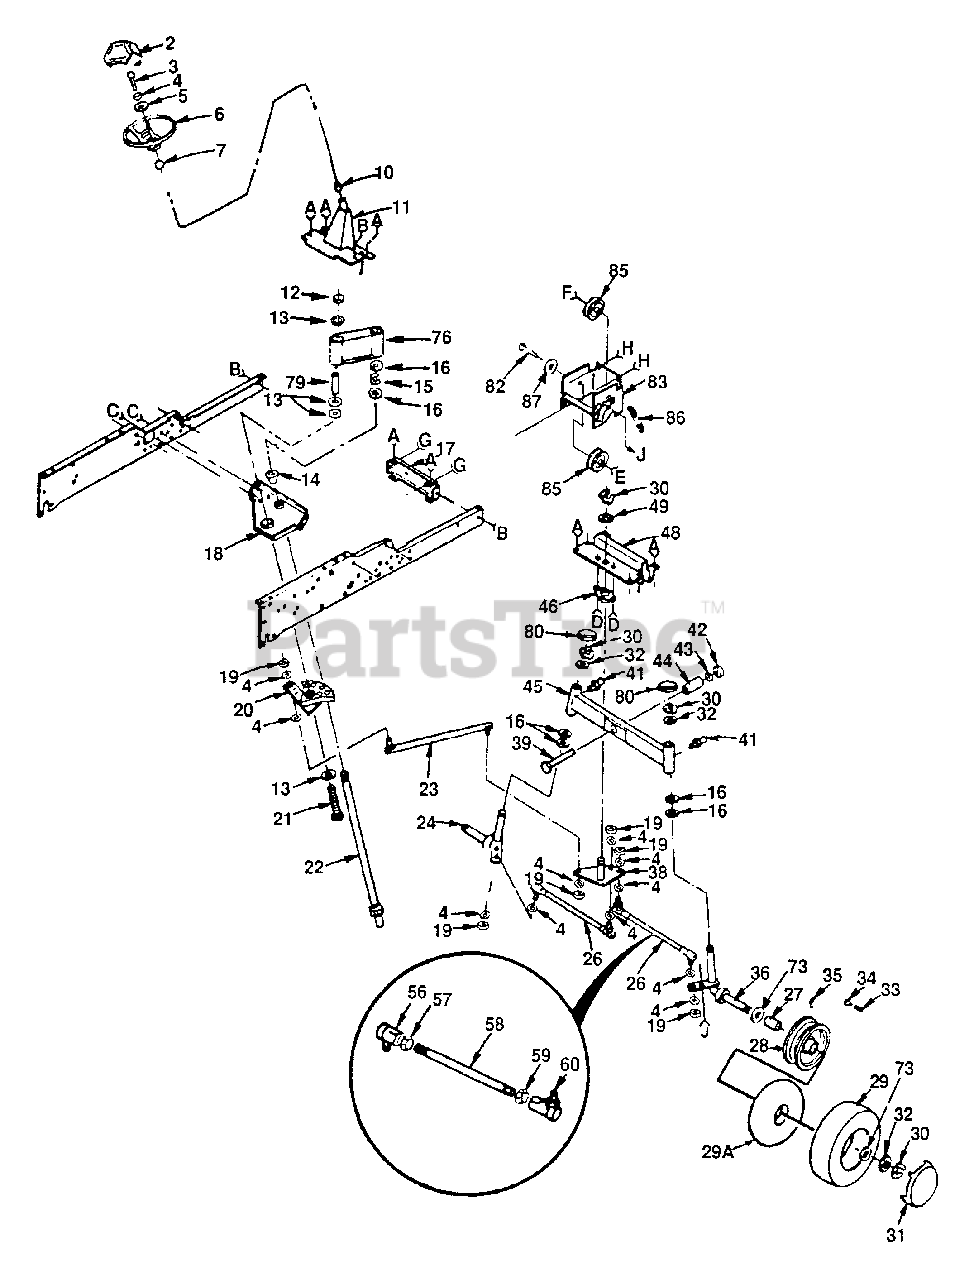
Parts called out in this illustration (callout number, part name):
2	Insert, Steering Wheel
3	Bolt, Hex 3/8-16 x 1 Grade 5
4	Washer, Lock 3/8
5	Washer 13/32 x 2-3/8 x 8 Gauge
6	Wheel, Steering
7	Adapter, Steering
11	Support Assembly, Steering
12	Locknut 1/2-13
13	Washer 17/32 x 1-5/8 x 10 Gauge
14	Bearing, Flanged
16	Bearing, Thrust
17	Bracket, Frame, Front
18	Bracket, Support, Steering
19	Nut, Hex 3/8-24
20	Sector Assembly
21	Bolt, Hex 1/2-13 x 5 Grade 5
22	Shaft, Steering
23	Link, Drag
24	Spindle, L.H.
26	Rod, Tie
28	Rim Assembly, Front
29	Tire
31	Cover, Wheel
32	Washer 25/32 x 1-5/8 x 16 Gauge
33	Cap, Valve
34	Stem, Valve
35	Fitting, Grease
36	Spindle, R.H.
38	Bellcrank Assembly
39	Bolt, Hex 5/8-11 x 2-3/4 Grade 5
41	Fitting, Grease
42	Nut, Hex 5/8-11
43	Washer, Lock 5/8
44	Tube, Pivot, Axle
45	Axle Assembly, Front
46	Bushing, Bellcrank
48	Bracket, Axle
49	Washer 29/32 x 1-1/4 x 16 Gauge
56	Joint, Tie Rod, L.H., Thread
57	Nut, Hex, Jam 3/8-24 L.H.
59	Nut, Hex, Jam 3/8-24
60	Joint, Tie Rod, R.H., Thread
73	Washer 25/32 x 1-1/4 x 16 Gauge
76	Collar Weld Assembly
80	Dust Cap Cover
82	Bolt, Hex 3/8-16 x 2
83	Bracket, Idler
85	Pulley, Idler
87	Washer 13/32 x 2-3/8 x 8 Gauge
